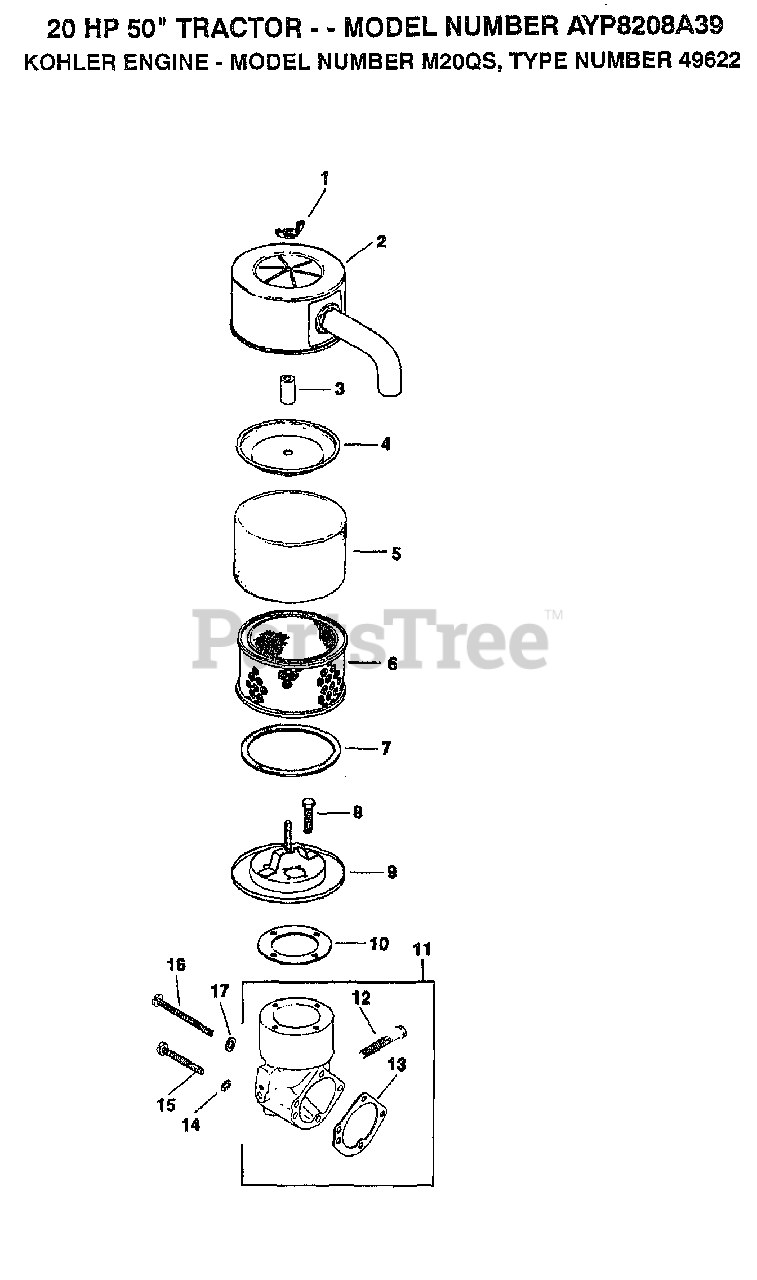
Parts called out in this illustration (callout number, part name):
1	WING NUT
2	COVER, AIR CLEANER
3	SEAL ELEMENT
4	COVER, AIR CLEANER ELEMENT
6	ELEMENT, AIR CLEANER
7	SEAL
8	SCREW
9	BASE, AIR CLEANER
10	GASKET
13	GASKET, AIR CLEANER ELBOW
14	WASHER
15	SCREW
16	SCREW
17	WASHER
